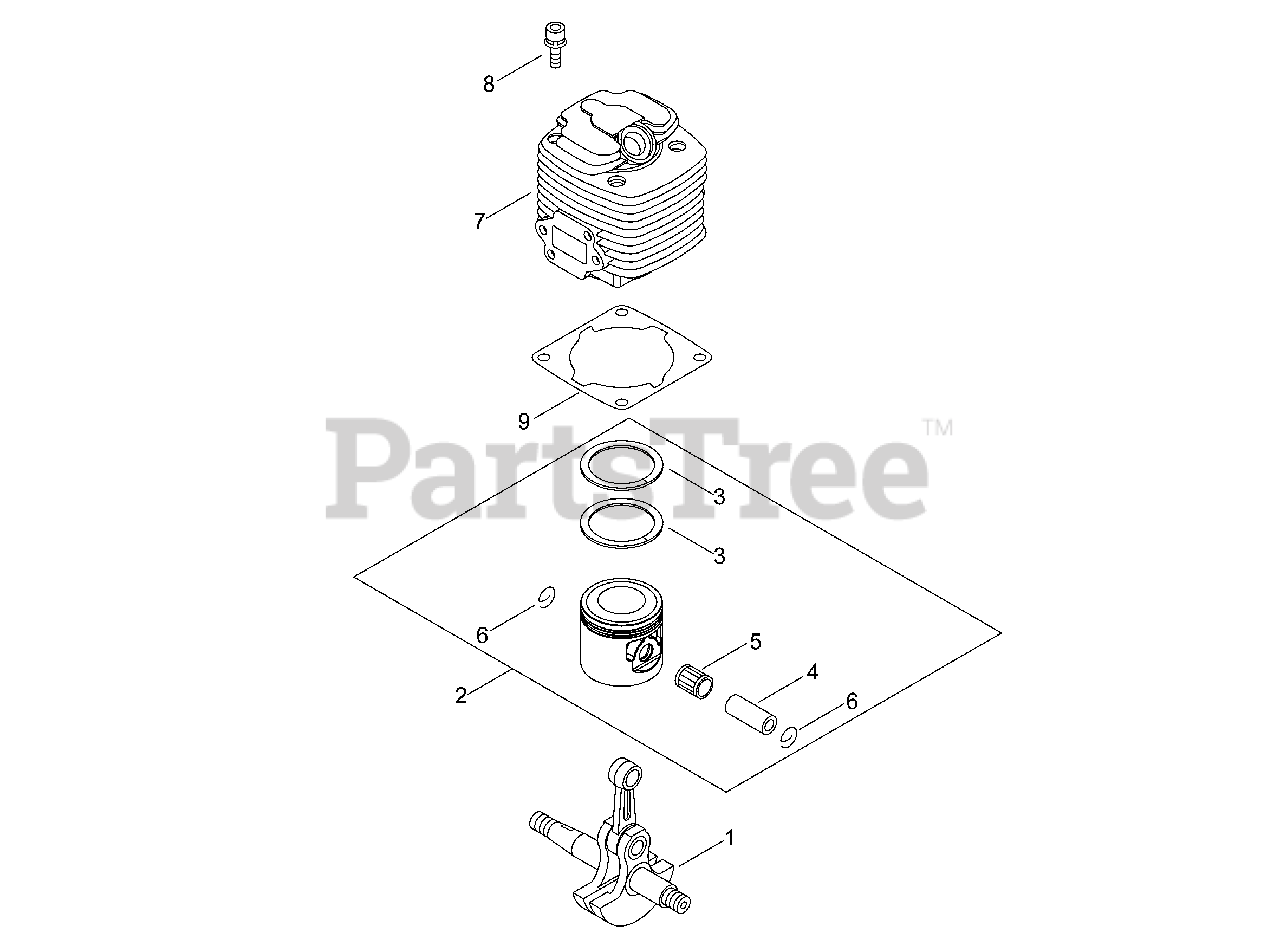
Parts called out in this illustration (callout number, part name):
1	CRANKSHAFT ASSY
2	PISTON KIT
3	RING, PISTON
4	PIN, PISTON 7×10×32.8
5	BEARING, NEEDLE
6	RING, SNAP 10
7	CYLINDER
8	BOLT 5×22
9	GASKET, CYLINDER
